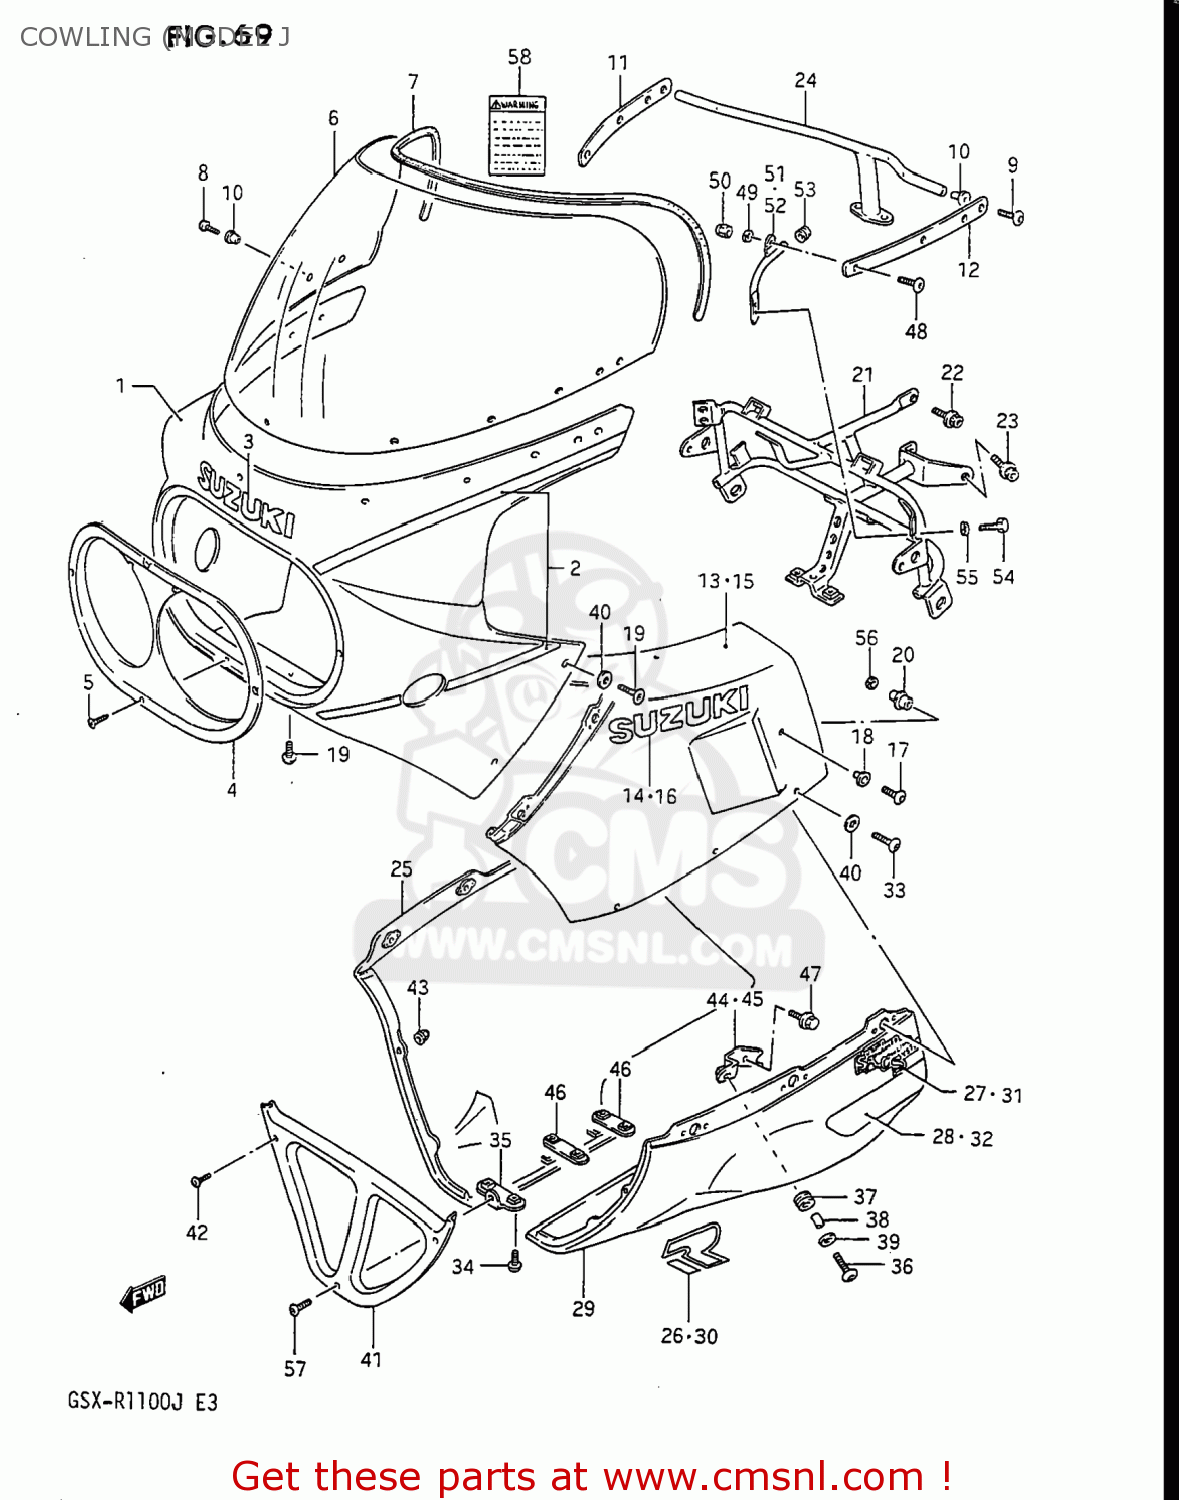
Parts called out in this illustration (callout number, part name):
1	BODY ASSEMBLY,COWLING
2	TAPE SET,COWLING,UPPER
3	EMBLEM,COWLING,UPPER (W)
4	COVER,COWLING,FRONT
5	SCREW
6	WINDSCREEN
7	MOLDING,SCREEN
8	SCREW(5X14)
9	SCREW(5X18)
10	NUT,COWLING SCREEN
11	PLATE,RR VIEW MIRROR,R
12	PLATE,RR VIEW MIRROR,L
13	COVER COMP,COWLING SIDE,RIGHT
14	EMBLEM
15	COVER COMP,COWLING SIDE,LEFT
16	EMBLEM
17	SCREW(6X12)
18	WASHER
19	SCREW(6X16)
20	CUSHION,COWLING
21	BRACE,COWLING FR
22	BOLT
23	BOLT
24	BRACE,COWLING BODY RR
25	COVER COMP,COWLING,LOWER
26	EMBLEM,COWLING,UNDER
27	EMBLEM,COWLING,UNDER
28	TAPE,COWLING
29	COVER COMP,COWLING,LOWER
30	EMBLEM,COWLING,UNDER
31	EMBLEM,COWLING,UNDER
32	TAPE
33	SCREW(6X16)
34	SCREW(6X16)
35	BRACE,COWLING LWR COVER
36	SCREW(6X20)
37	CUSHION
38	SPACER
39	WASHER(6.5X18X1)
40	WASHER
41	COVER,COWLING,LOWER,FRONT
42	SCREW(5X14)
43	NUT
44	BRACE,COWLING LWR,R
45	BRACE,COWLING LWR,L
46	BRACE,COWLING LWR COVER RR
47	BOLT
48	SCREW(6X16)
49	WASHER,LOCK
50	NUT 6MM
51	BRACE,MIRROR,R
52	BRACE,MIRROR,L
53	PLUG(OD:12)
54	BOLT 6X16
55	WASHER,LOCK
56	WASHER
57	SCREW(6X16)
58	LABEL (WARNING SCREEN)
